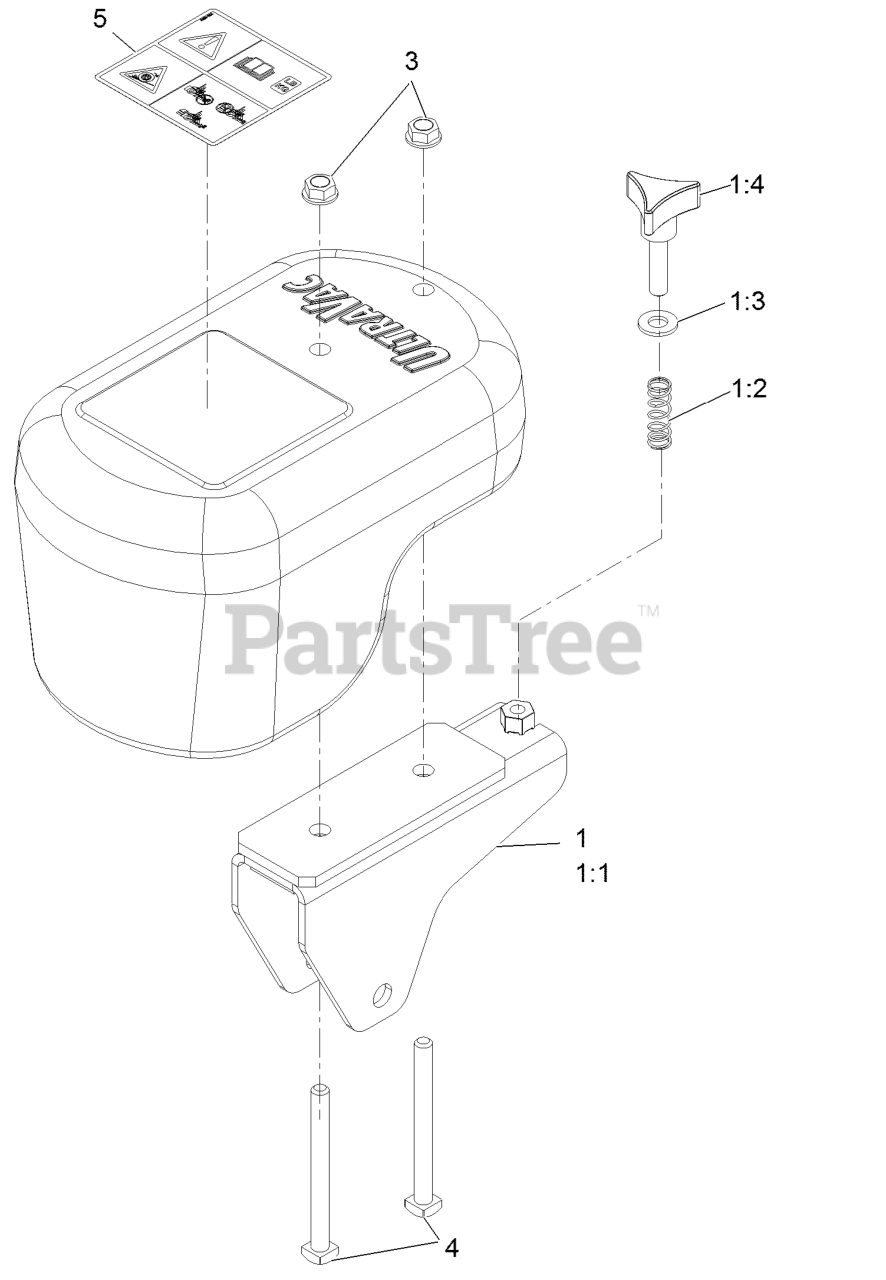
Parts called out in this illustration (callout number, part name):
1	ASM,Caster Weight Bracket
1:1	Wld,Caster Weight Bracket
1:3	Washer-3/8 SAE
3	Nut-Whizlock 3/8-16
4	Bolt-Square Hd 3/8-16 X 4
5	Decal-Warning, Traction
